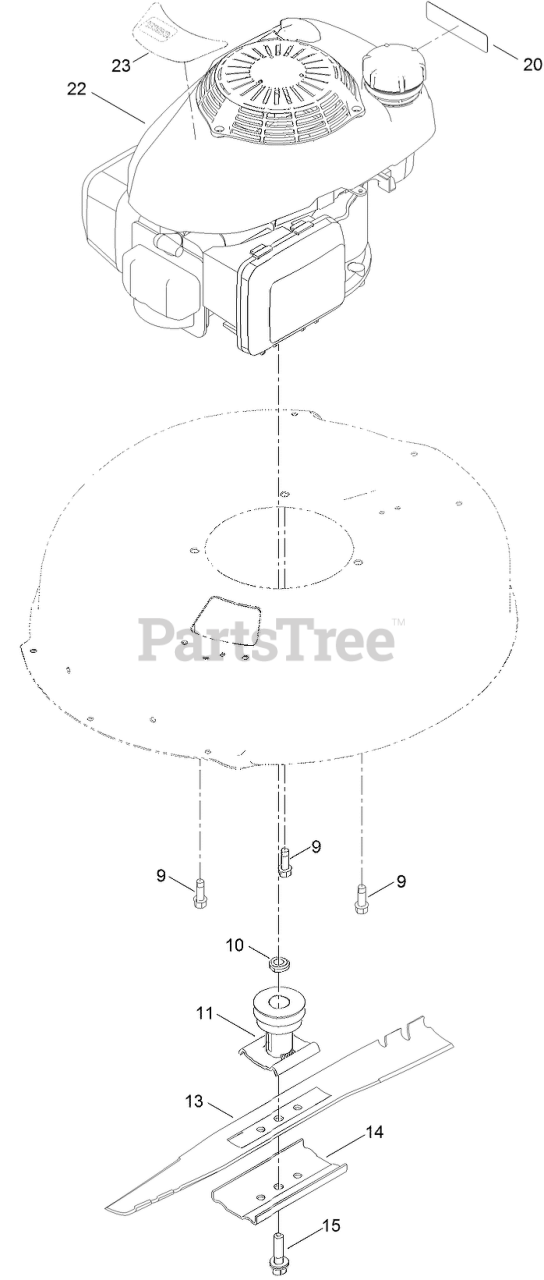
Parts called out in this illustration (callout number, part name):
9	SCREW-TAPTITE
10	SPACER-DRIVER
11	DRIVER-BLADE
13	BLADE-21IN
14	SUPPORT-BLADE
15	BOLT-BLADE
20	DECAL-ARRESTER, SPARK
23	DECAL-SHROUD, HONDA
